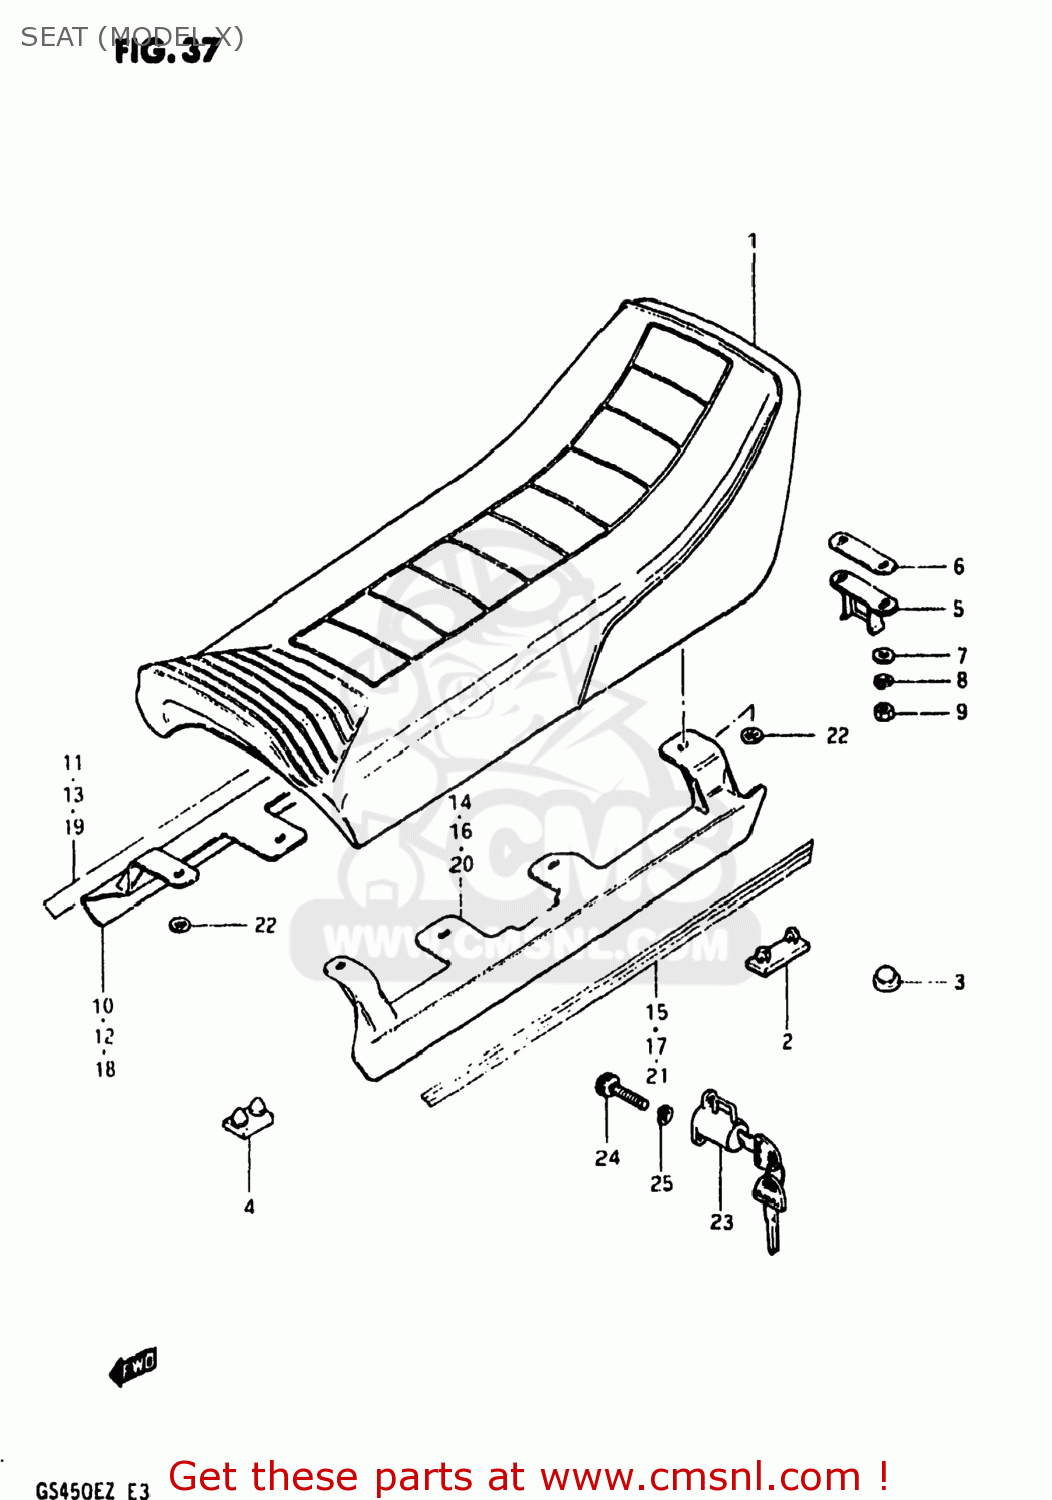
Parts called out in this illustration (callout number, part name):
1	SEAT ASSEMBLY
2	CUSHION
3	CUSHION
4	CUSHION
5	STRIKER,SEAT LOCK
6	SHIM,SEAT LOCK STRIKER
7	WASHER
8	LOCK WASHER
9	NUT 6MM
10	MOLDING,SEAT
11	TAPE,RIGHT
12	MOLDING,SEAT
13	TAPE,RIGHT
14	MOLDING,SEAT
15	TAPE,LEFT
16	MOLDING,SEAT
17	TAPE,LEFT
18	MOLDING,SEAT
19	TAPE,RIGHT
20	MOLDING,SEAT
21	TAPE,LEFT
22	NUT
23	LOCK ASSEMBLY,HELMET
24	BOLT 6X11
25	LOCK WASHER
